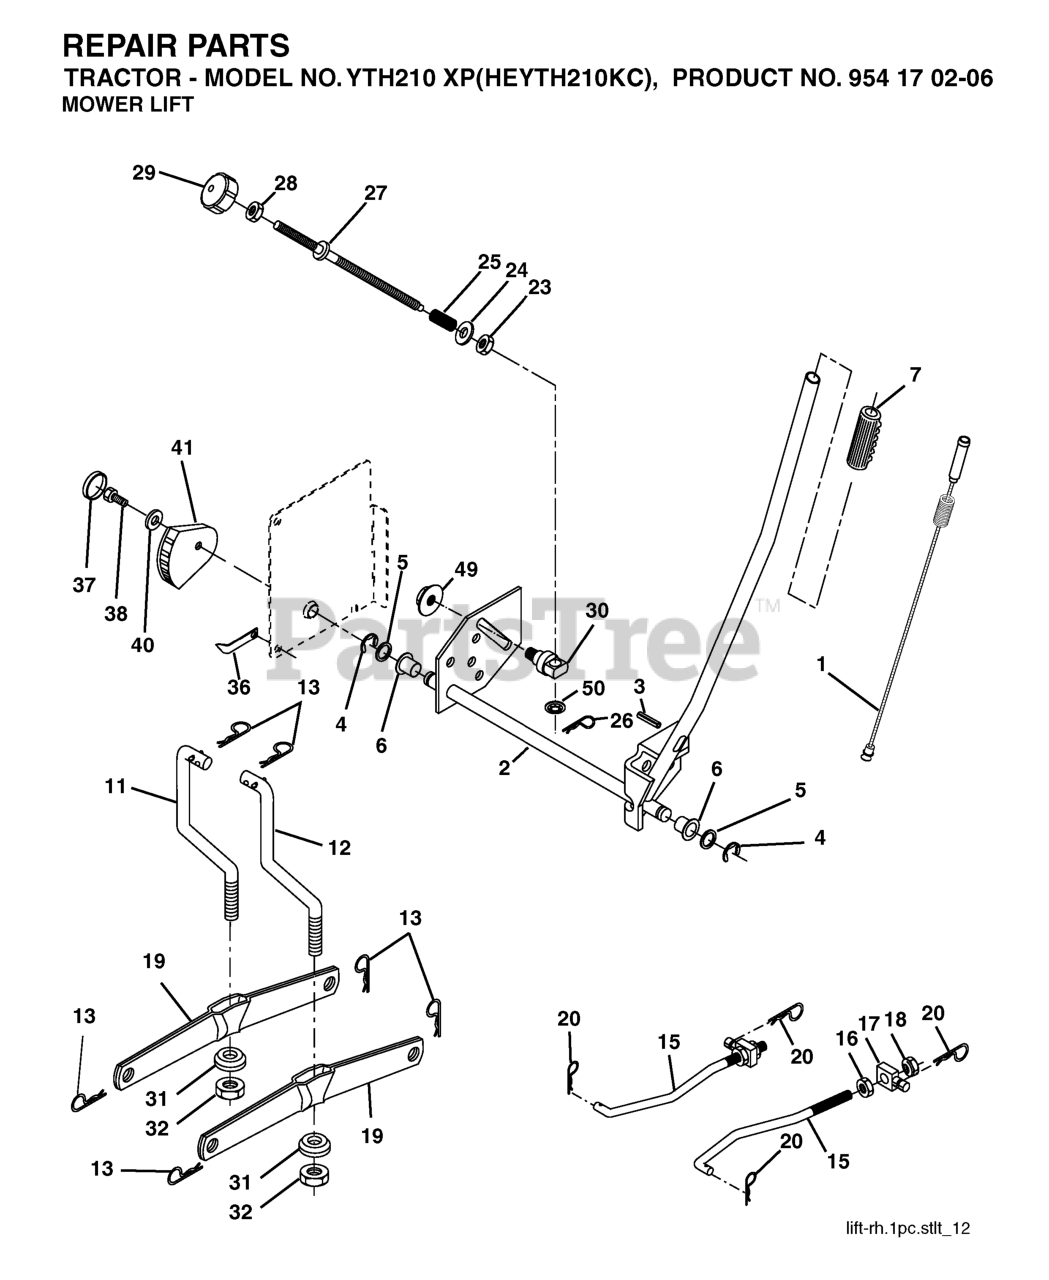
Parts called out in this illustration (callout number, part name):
1	WIRE ASM INNER W/ PLUNGER LT
2	SHAFT ASM R HANDLE
3	PIN GROOVE.
4	RETAINING RING LT
6	BEARING.NYLON
7	GRIP HANDLE
8	PLUNGER BUT KIT
11	LINK LIFT LH
12	LINK LIFT RH
13	RETAINER-SPRNG RB
15	LINK.SUSPENSION.FRONT
16	NUT.HEX.JAM.1/2-13
18	NUT.LK.W/WSH.1/2.
19	ARM.REAR.SUSPENSION
20	SPRING RETAINER
25	SPRING**
26	RETAINER CLIP
27	ROD ADJ LIFT
28	NUT
29	KNOB INF 3/8-16
31	BEARING.PIVOT.LIFT
32	NUT CROWNLOCK 3/8-24
36	POINTER, HEIGHT INDICATOR(2 2)
38	SCREW 5/16-18X1
41	IND. HEIGHT STLT
49	NUT
50	NUT PUSH M
